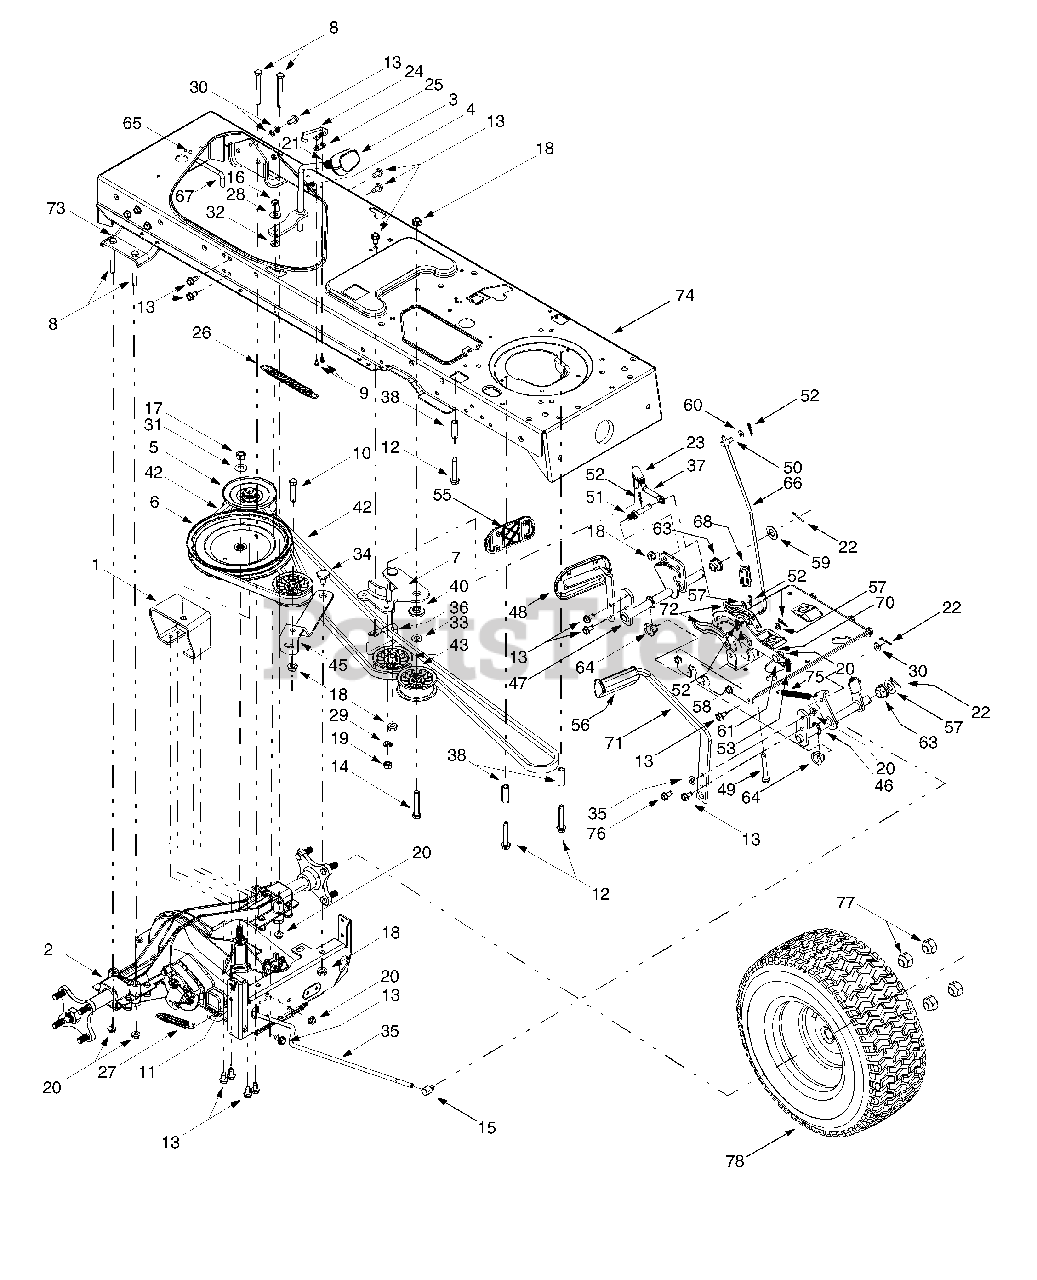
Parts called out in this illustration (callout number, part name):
1	Variable-speed Bracket Assembly
2	Two-Speed Transmission Assembly
3	Shifter Knob
4	Shift Lever
5	Variable Speed Pulley Assembly
6	Transmission Pulley, 8.5 x .5 - 36
7	Double-idler Bracket
8	Hex Cap Screw, 5/16-18 x 3
9	Self Tapping Screw, #8-18 x .5
10	Hex Cap Screw, 3/8-16 x 1.75
11	Hex Cap Screw, 5/16-18 x 1.25
12	Self-tapping Screw, 1/4-20 x 1.5
13	Self Tapping Screw, 5/16-18 x .625
14	Hex Cap Screw, 3/8-16 x 2.25
15	Ferrule, 5/16 x .312 Dia.
16	Hex Jam Nut, 3/8-16
17	Hex Nut, 7/16-20
18	Flange Lock Nut, 3/8-16
19	Hex Nut, 3/8-16
20	Flange Lock Nut, 5/16-18
21	Hex Jam Nut, 3/8-16
22	Cotter Pin
23	Ball Joint, 3/8-24
24	Spring Switch
25	Insulator Nut Plate
26	Extension Spring, .62 Dia. x 6.12
27	Extension Spring, .59 OD x 4.0
28	Bell Washer, .401 x .870 x .063
29	Lock Washer, 3/8
30	Flat Washer, 5/16
31	Bell Washer, .45 x 1.0 x .062
32	Flat Washer, .44 x .75 x .06
33	Flat Washer, .407 x .812 x .135
34	Shoulder Screw, .625 Dia. x .21
35	Brake Rod
36	Belt Guard
37	Idler Adjustment Rod, 3/8
38	Spacer, .372 x .26 x 1.03
40	Shoulder Spacer, .380 ID
42	Drive Belt, Lower 90.8" Long
42	Drive Belt, Upper 41.5" Long
43	Flat Idler, 2.75 OD
46	Brake Control Shaft Assembly
47	Speed Control Shaft Assembly
48	Drive Pedal Assembly
49	Self Tapping Screw, 5/16-18 x 2.5
50	Ferrule, 1/4-20
51	Pin, 3/8-16 x 2.43
52	Cotter Pin
53	Compression Spring, .34 OD x 1.0
55	Drive Pedal Pad
56	Brake Pedal Pad
57	Flat Washer, .281 x .5 x .0625
58	Flat Washer, 9/32 x 1/2 x 1/16
59	Flat Washer, .64 x 1.24 x .06
60	Flat Washer, .344 x .062 x .03
61	Shoulder Screw, .437 x 1.62
63	Hex Flange Bearing
64	Split Hex Flange Bearing
65	Self Tapping Screw,1/4-20 x .5
66	Brake Lock Control Rod
67	Transmission Belt Guard Rod
68	Spacer, 5/16 x 1.54
70	Drive Lockout Bracket
76	Hex Screw, 5/16-18 x .75
77	Lug Nut, 7/16-14
